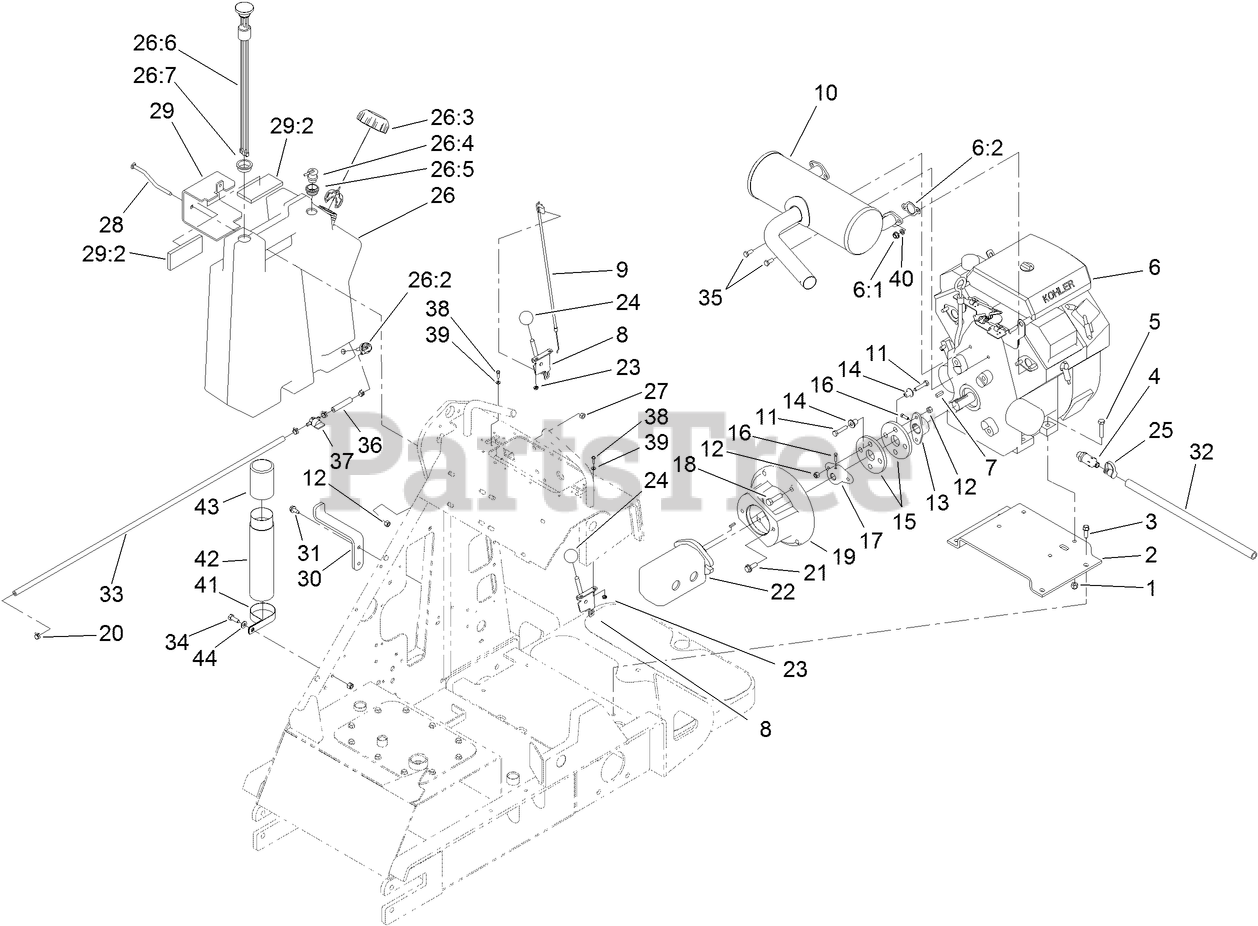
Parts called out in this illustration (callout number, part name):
1	NUT-LOCK, NI
2	MOUNT-ENGINE
3	SCREW-TAPTITE
4	VALVE-DRAIN, OIL
5	SCREW-HH
6	ENGINE-KOHLER, CH20S
6:1	NUT-HF
6:2	GASKET-EXHAUST
7	KEY-SQUARE
8	LEVER-CONTROL
9	CABLE-CONTROL
10	Muffler
11	SCREW-HH
12	NUT-LOCK, NI
13	HUB-ENGINE
14	SPACER
15	COUPLING-RUBBER
16	SCREW-SQH
17	HUB-PUMP
18	SCREW-HH
19	MOUNT-PUMP
20	CLAMP-HOSE
21	SCREW-HHF
22	HYD PUMP ASM
23	NUT-KEPS
25	CAP-DUST
26	RH FUEL TANK ASM
26:2	FITTING-FUEL, BULKHEAD
26:3	CAP-FUEL
26:4	VALVE-ROLLOVER
26:5	GROMMET
26:6	GAUGE-LEVEL, FUEL
26:7	GROMMET
27	NUT-HEX, SIDE DEFORM
28	BOLT-MOUNT
29	RH TANK MOUNT ASM
29:2	PAD-FOAM
30	MOUNT-TANK, BOTTOM
31	SCREW-HWHTF
33	HOSE-FUEL
34	SCREW-HH
35	SCREW-HH
36	HOSE-FUEL
37	VALVE-FUEL
39	WASHER-FLAT
40	WASHER-LOCK
41	CLAMP-R
42	TUBE-MANUAL
43	CAP-HOUSING
44	WASHER-PLAIN
